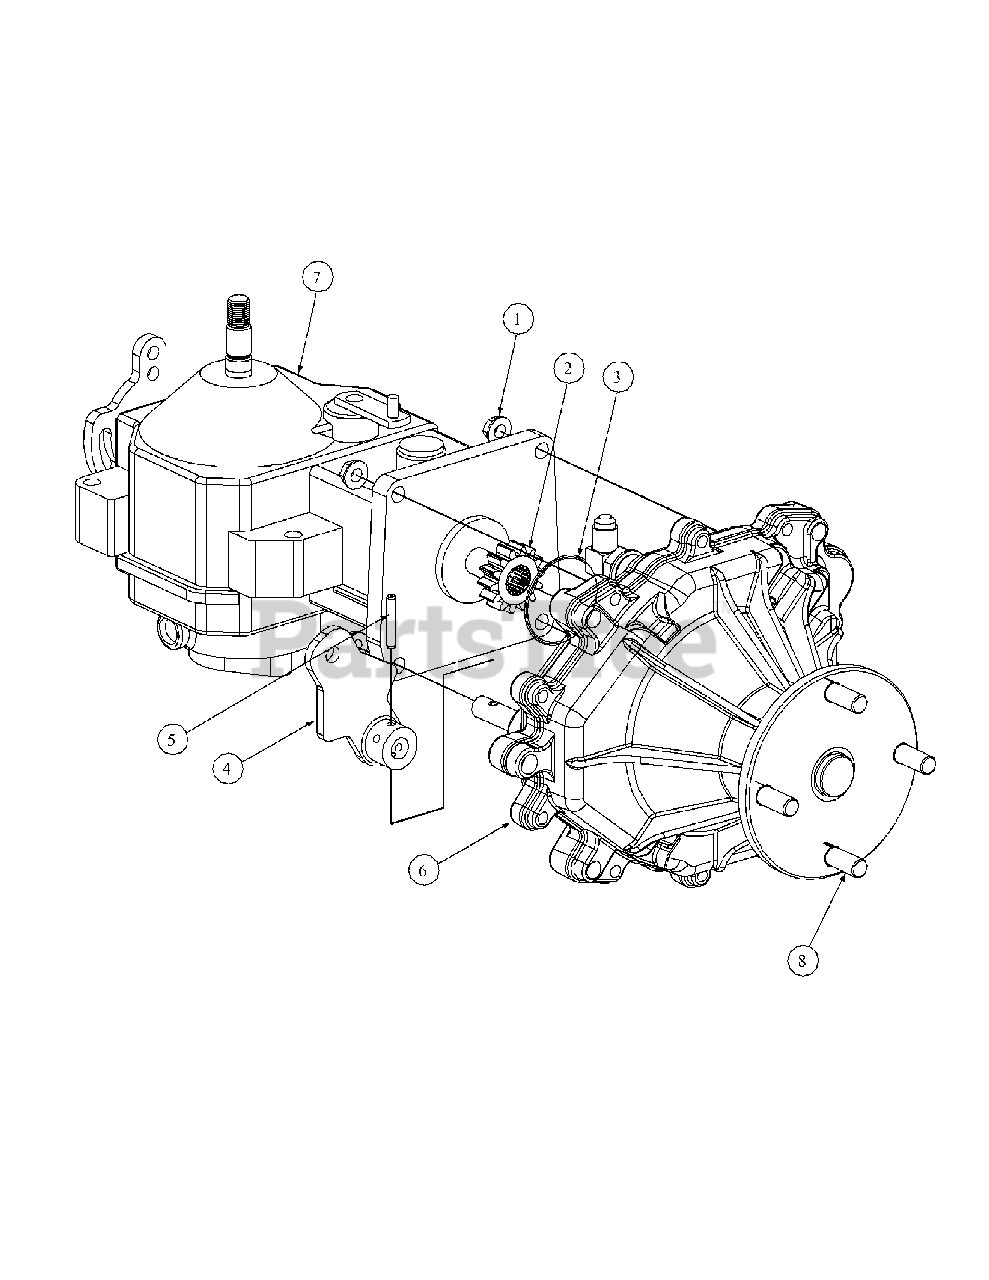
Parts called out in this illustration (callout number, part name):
1	Hex Flange, Lock Nut, 5/16-18
2	Gear, Spur, 14T
3	O-Ring, 2.00 x .070
4	Lever, Bracket, Park
5	Pin, Spirol, 3/16 x 1.25 HD
6	Transmission Assembly
8	Rib Neck Stud
